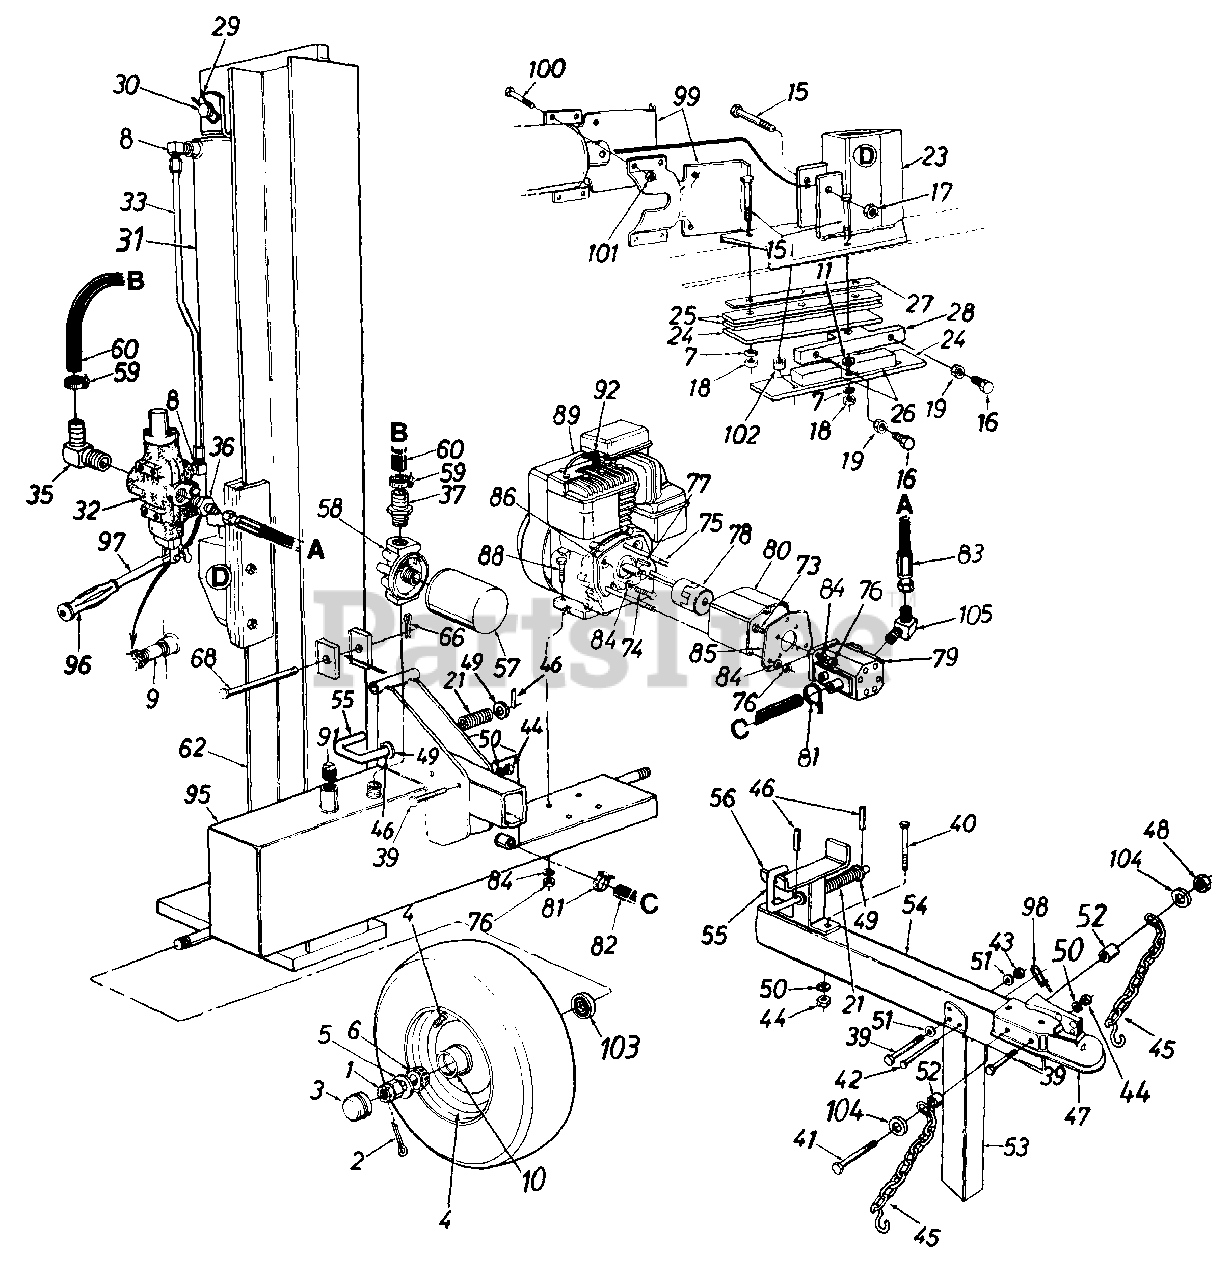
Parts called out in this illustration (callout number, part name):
1	Slotted Nut 3/4-16 Thd.
2	Cotter Pin 5/32" Dia. x 1-1/4" Lg.
3	Hub Cap
5	Fl-Wash .76" I.D. x 1.5" O.D.
6	Bearing Cone
7	L-Wash. 1/2" I.D.
8	90 Deg. Solid Male Adapter
9	Pipe Nipple 1/2 NPT
10	Bearing Cup
11	Fl-Wash .531" I.D. x .94" O.D.
15	Hex Bolt 1/2-20 x 2.75" Lg. (Grade 8)
16	Hex Bolt 3/8-24 x 1.5" Lg.
17	Hex L-Nut 1/2-20 Thd.
18	Hex Nut 1/2-20 Thd.
19	Hex Jam Nut 3/8-24 Thd. (Grade 5)
21	Comp. Spring 4" Lg.
29	External Cotter Pin
30	Cylinder Mounting Pin
33	Metal Pressure Tube
35	Return Elbow
36	Adapter
37	3/4" Hose Barb.
39	Hex Bolt 3/8-16 x 2.75" Lg. (Grade 8)
40	Hex Bolt 3/8-16 x 4" Lg.
41	Hex Bolt 3/8-16 x 4" Lg. (Grade 5)
42	Clevis Pin 5/16 x 2.5" Lg.
43	Hex L-Nut 3/8-16 Thd.
44	Hex Nut 3/8-16 Thd.
45	Chain - Tow Hitch
46	Roll Pin
47	Hitch Coupler
48	Hex Ctr. L-Nut 3/8-16 Thd.
49	Fl-Wash .635" I.D. x .93" O.D.
50	L-Wash. 3/8" I.D.
51	Fl-Wash .406" I.D. x .75" O.D.
52	Spacer 3/8" I.D. x .625" O.D.
55	Locking Rod
57	Fllter Element
58	Fllter Head
59	Hose Clamp 5/8"
60	Return Hose 3/4" I.D. x 44" Lg.
68	Hinge Pin 112 x 4.8" Lg.
73	Hex Bolt 5/16-24 x 1" Lg.
74	Hex Bolt 5/16-24 x .62" Lg.
75	Hex Bolt 5/16-24 x 4" Lg.
76	Hex Nut 5/16-24 Thd.
77	Sq.-Key 3/16" x .75"
78	Flexible Coupling
79	Gear Pump
80	Coupling Shield
81	Hose Clamp
82	Suction Hose
83	High Pressure Hydraulic Hose
84	L-Wash. 5/16" I.D.
88	Hex Bolt 5/16-24 x 1.75" Lg.
89	Engine
91	L-Vent Pipe Plug
92	Spark Plug Boot
97	Control Handle
98	Spring Pin
101	Hex L-Nut 3/8-16 Thd.
102	Spacer 1/2" I.D. x .68" Lg.
103	Bearing Seal Only
104	Fl-Wash. 3/8" I.D. x .87" O.D.
105	90 Deg. Male Adapter
